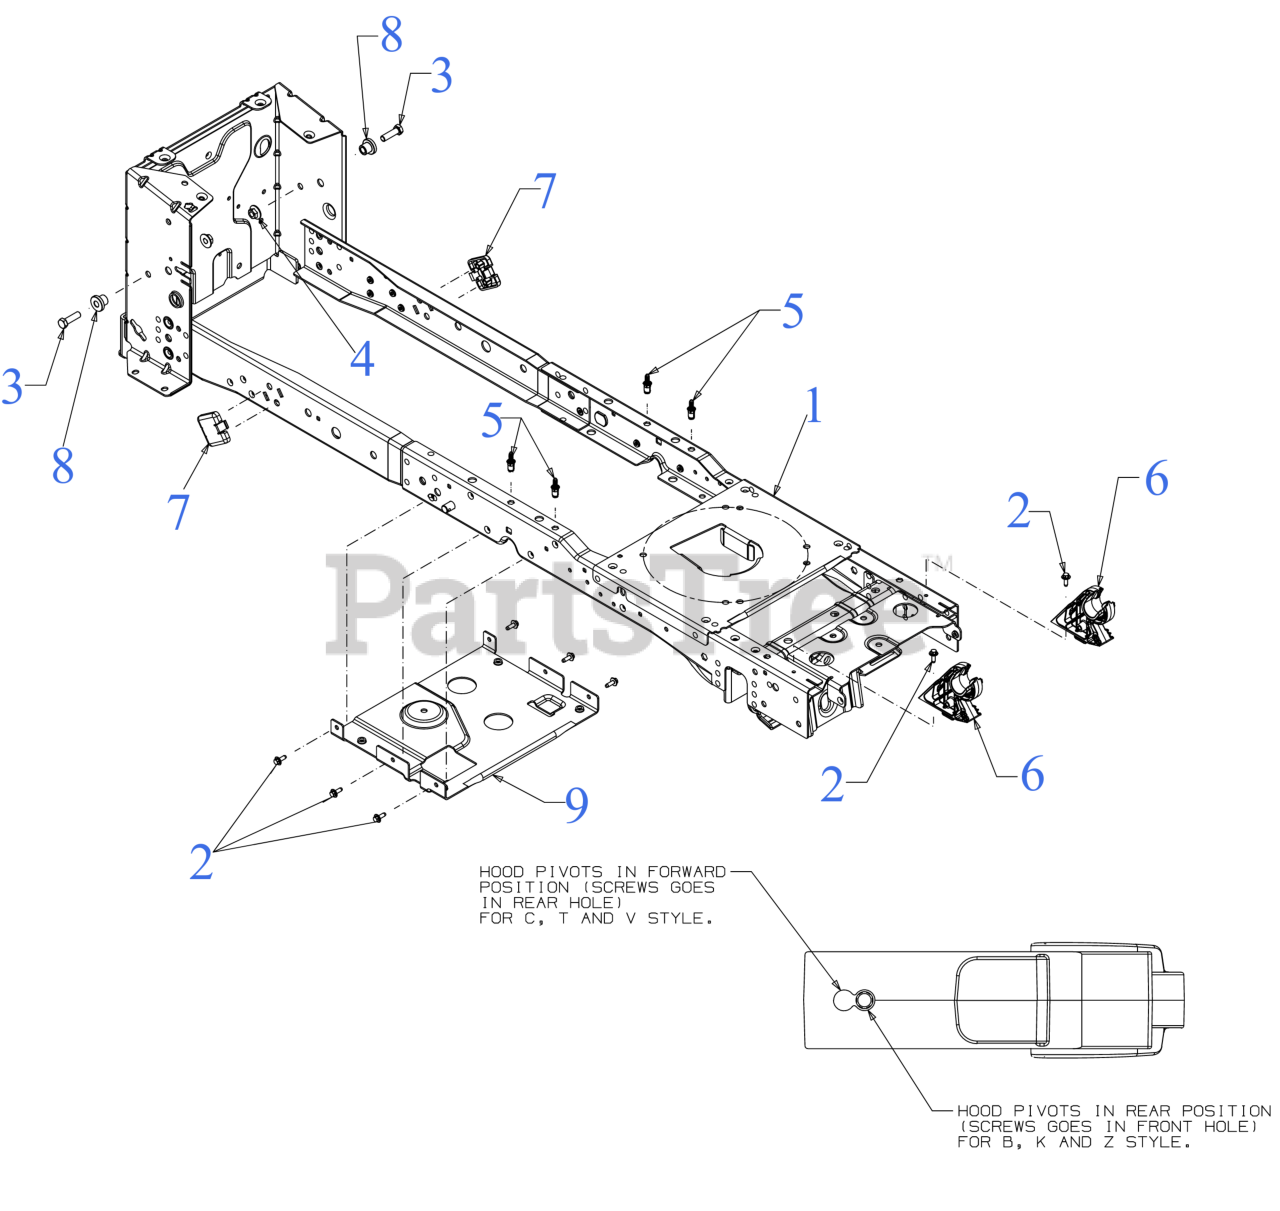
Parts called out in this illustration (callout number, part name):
1	DIFF LOCK FRAME ASSEMBLY
2	SCREW M6-1 x .625
3	SCREW 3/8-16 x 1.25 GR5
4	FLANGE LOCK NUT
5	RIVET-HEX STUD 1/4-20 FRM
6	HOOD PIVOT BRACKET
7	LIFT ROD WEAR PAD
8	SHOULDER SPACER
